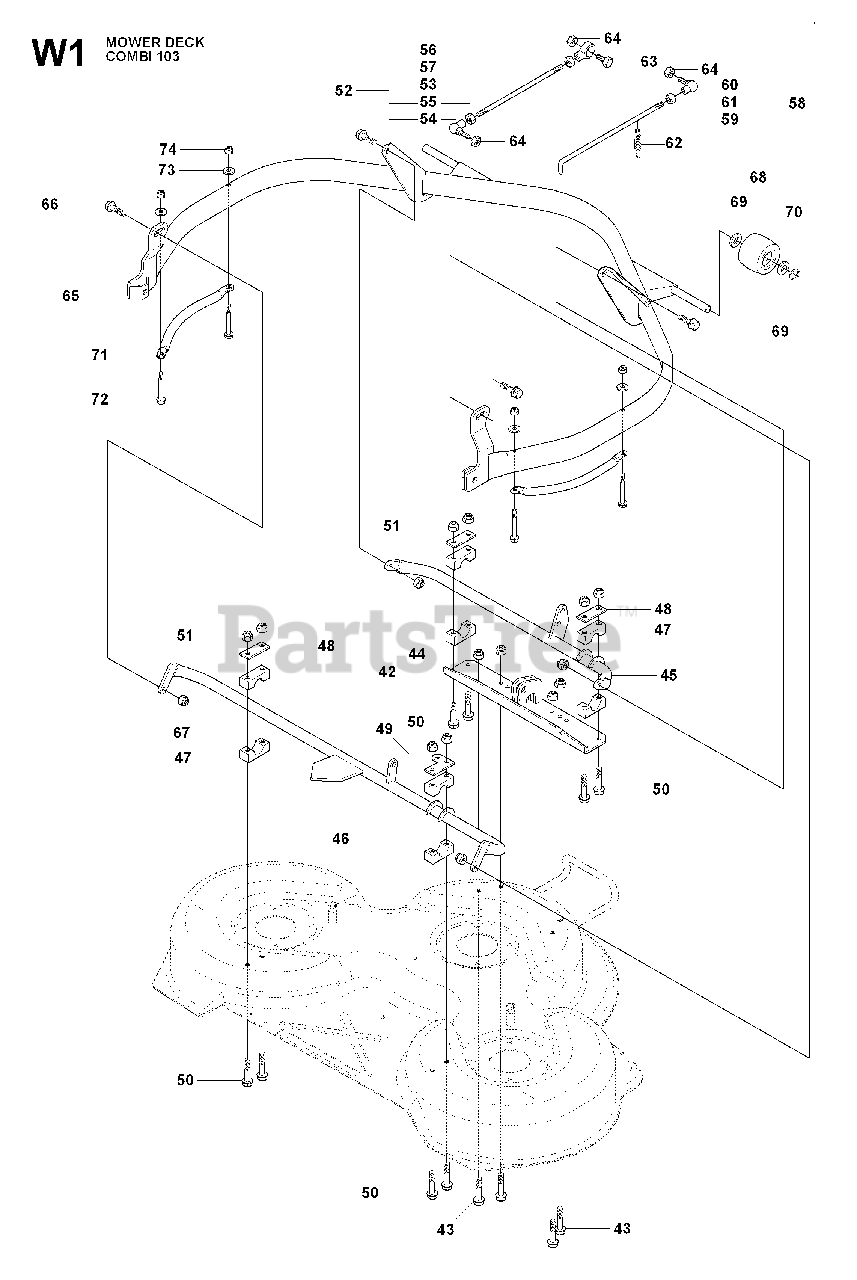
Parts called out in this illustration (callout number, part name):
44	LOCKNUT M8
51	LOCKNUT M8
52	PARALLEL RODY ASSY
58	CLUTCH ROD ASSY
67	LOCKNUT M8
68	DECK ROLLER, FRONT
70	RETAINING RING SGA 15
73	WASHER
74	LOCKNUT M6
